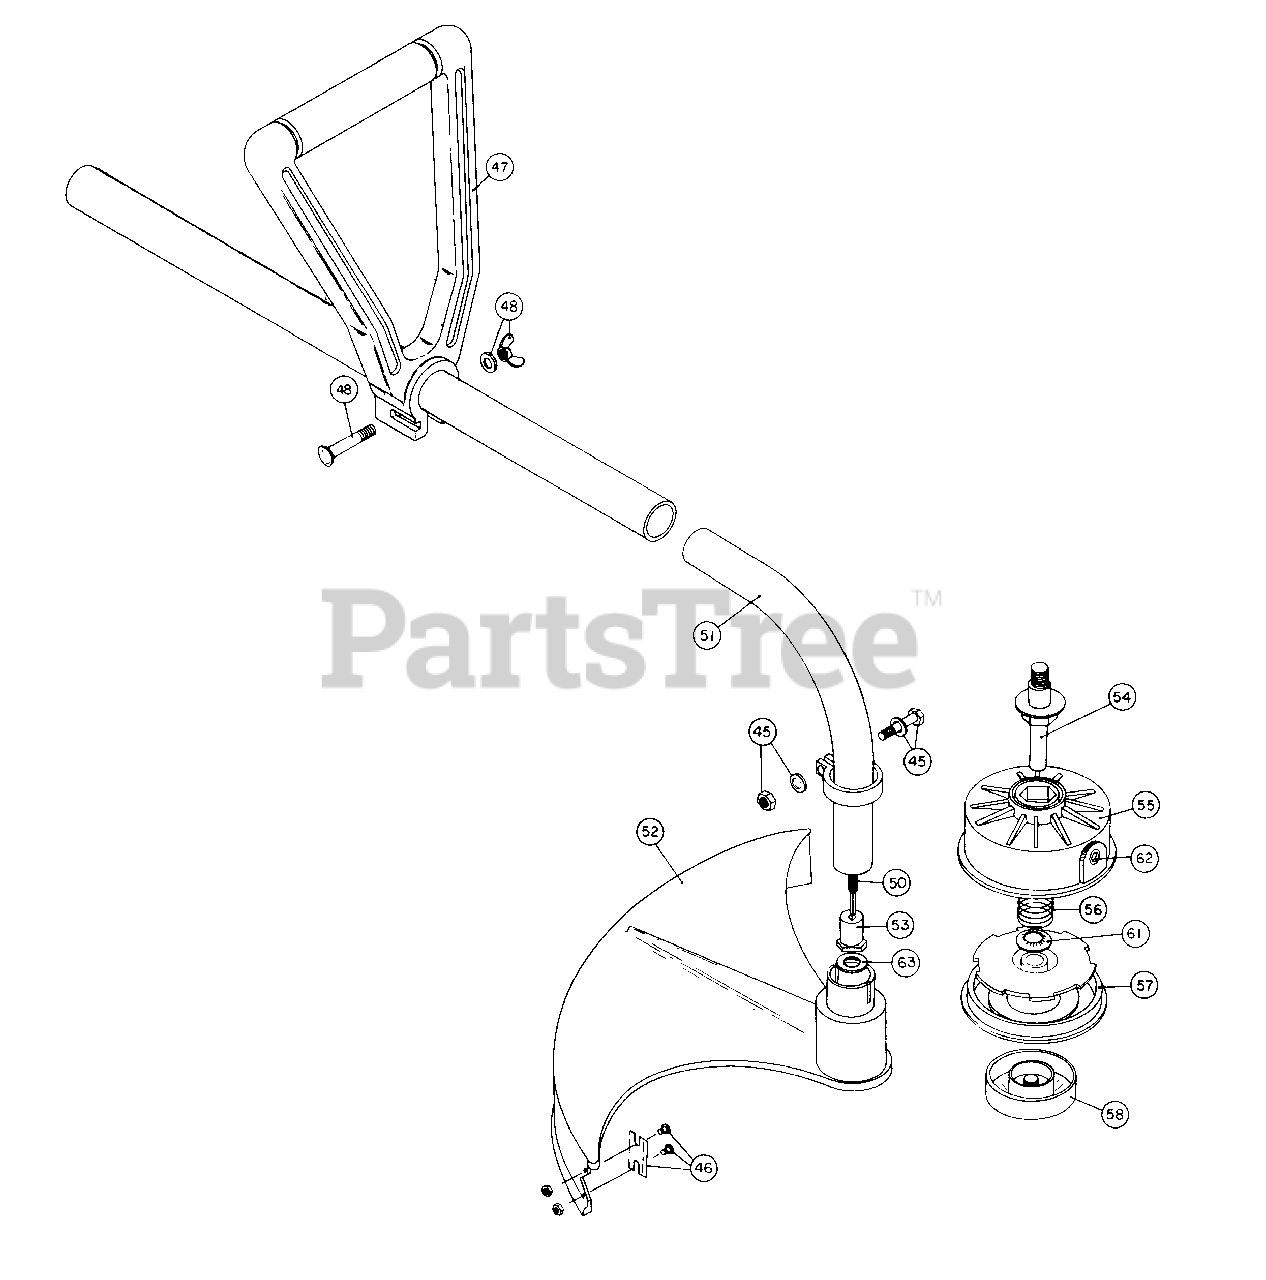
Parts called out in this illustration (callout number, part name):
45	Lower clamp assembly
46	Blade assembly
47	D-handle
48	D-handle hardware assembly
50	Flexible drive shaft
51	Drive shaft housing assembly
52	Guard and bearing housing assembly
53	Square drive nut
54	Spool shaft assembly
55	Outer spool assembly
57	Inner reel
58	Bump head knob assembly
61	Retainer (10 pack)
